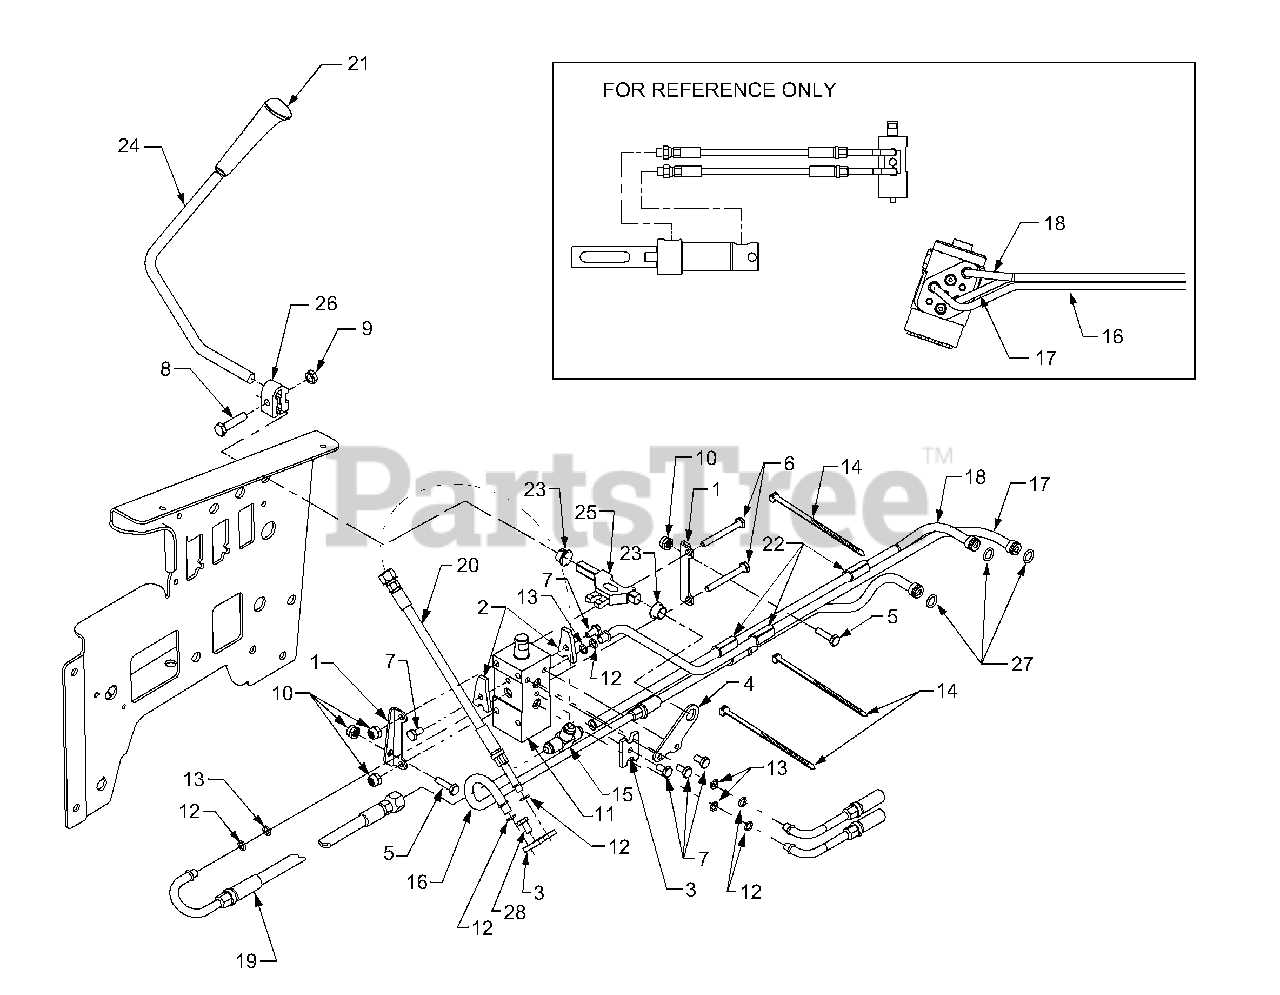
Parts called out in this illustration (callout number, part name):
1	Bracket, Valve Mounting
2	Clamp, Side Valve
3	Clamp, Double Valve
5	Screw, Hex Cap 1/4-20 x 1.0 GR5
6	Screw, Hex Cap 1/4-20 x 2.25 GR5
7	Screw, Hex Cap 1/4-20 x .50 GR5
8	Screw, Hex Cap 5/16-18 x 1.375 GR5
9	Nut, Hex Insert Lock, 5/16-18
10	Nut, Hex Flange Lock, 1/4-20
11	Valve, Hydraulic
12	O-Ring, Backup
13	O-Ring
14	Cable Tie
15	T-Fitting, 9/16-18 Thrd.
16	Tube, Hydraulic (Pump to Strng)
17	Tube, Hydraulic (Aux. from Strng)
18	Tube, Hydraulic (Strng Return)
19	Tube, Hydraulic (Aux Return)
20	Tube, Hydraulic (Return to Pump)
21	Knob, Lift
22	Rubber Spacer
23	Bearing, Nylon Flange
24	Handle, Center Lift Valve
25	Link, Lift
26	Clamp, Handle
27	O-Ring, .426 x .566 x .070
28	Screw, Hex Cap 1/4-20 x .62 GR5
